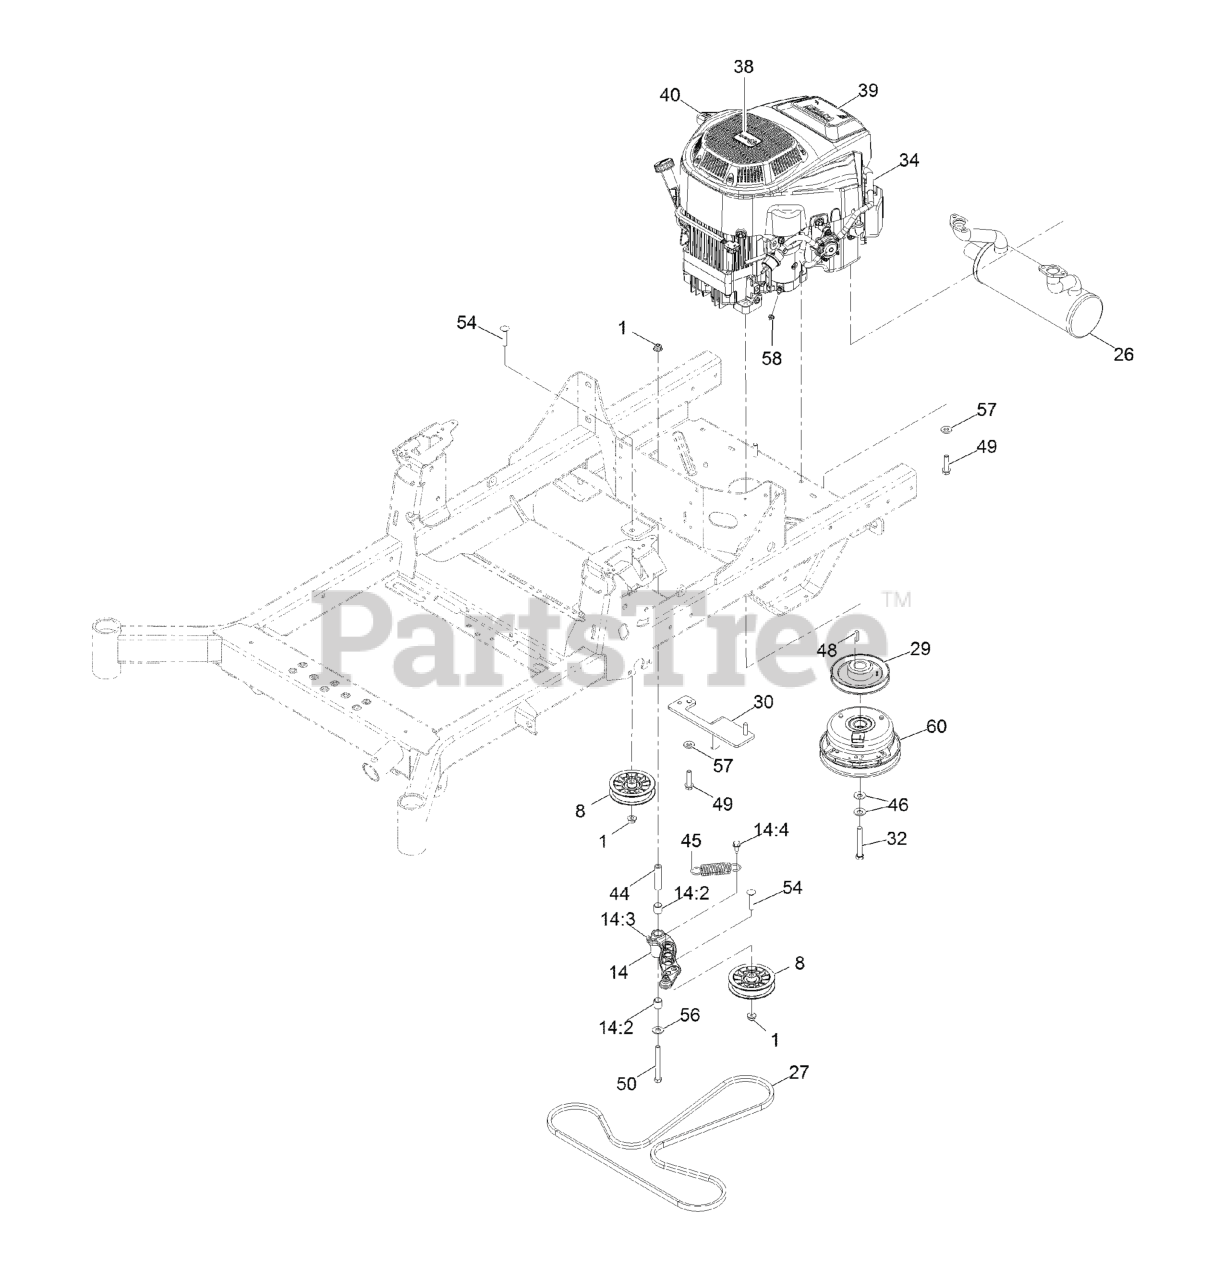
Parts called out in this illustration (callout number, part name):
1	NUT-HF, NI
8	PULLEY-FLAT IDLER
14	IDLER ARM ASM
14:2	SLEEVE-BEARING
14:3	FITTING-GREASE, 90 DEG
14:4	SCREW-THD ROLL, HWH
26	MUFFLER
27	BELT-V
29	SHEAVE-ENGINE
30	ANCHOR-CLUTCH
32	SCREW-HH W/LOCTITE
34	ENGINE-2P77F
39	DECAL-708CC V-TWIN ENGINE
40	DECAL-DRAIN, OIL
44	BUSHING-PIVOT, IDLER
45	SPRING-EXTENSION
46	WASHER-SPRING
49	SCREW-HWH
50	SCREW-HH
54	SCREW-CARR
56	WASHER-FLAT
57	WASHER-BELLEVILLE
60	CLUTCH - 1.00 HD
